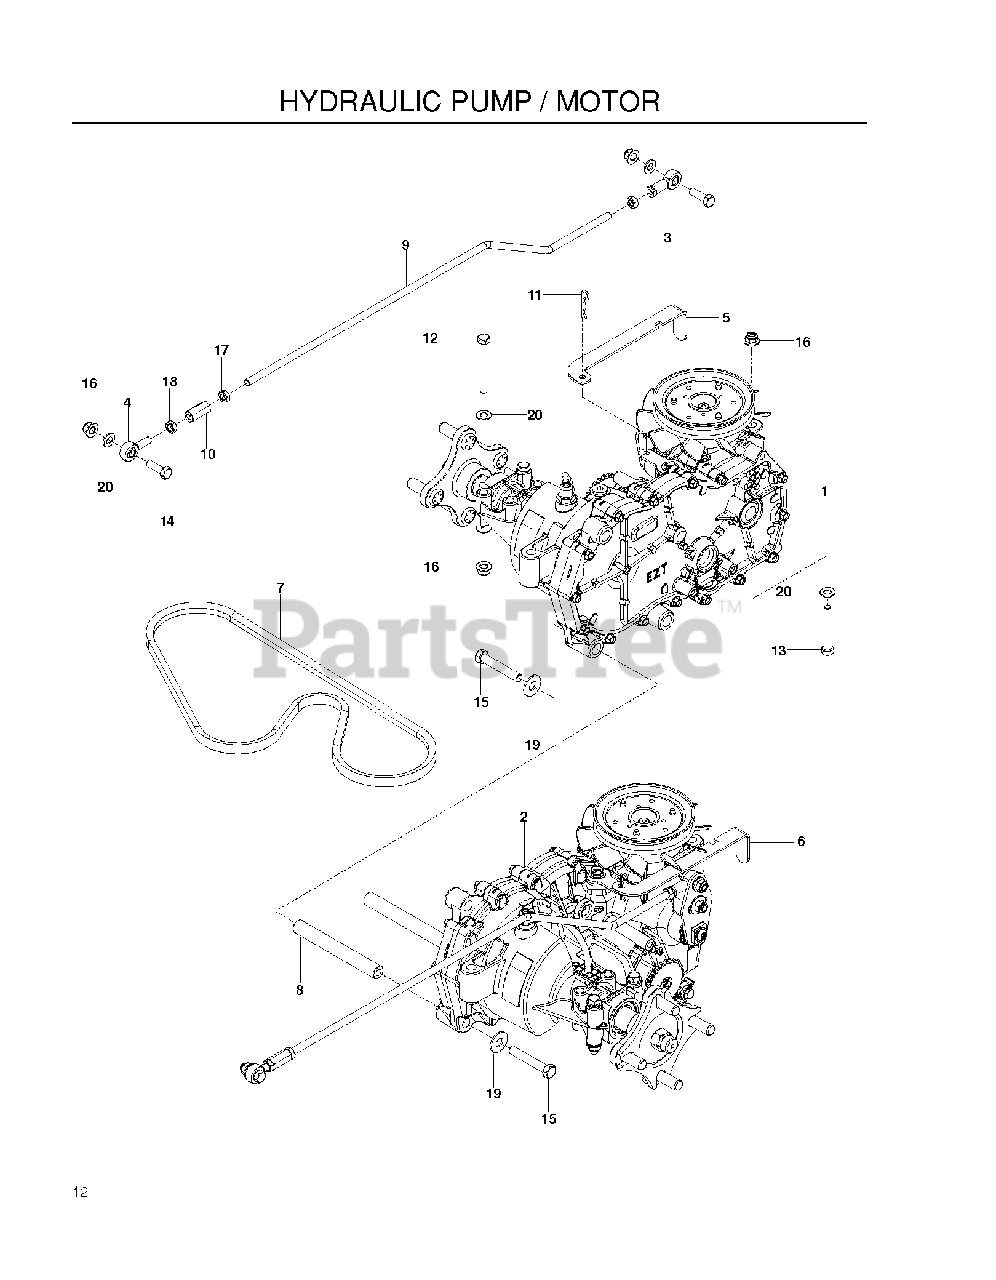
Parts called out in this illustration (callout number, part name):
1	HG_HYDRO RH
2	HG_HYDRO LH
3	RH ROD END
4	RB ROD.END.LH
5	RELEASE LEVER RH
6	RELEASE LEVER LH
7	BELT, EL 51.O4
8	SPACER, HYDRO
9	CONTROL ROD
10	ROD END COUPLER
11	HAIRPIN #2
12	HCS 5/16C X 2-3/4
14	HCS 5/16C X 1
15	HCS 3/8C X 2 1/4
16	5/16-18 NYLOC FLANGE NUT
17	NUT 5/16-24 UNF HEX JAM
18	NUT 5/16F LEFTHAND
19	RP WASHER 3/8 FLAT
20	FLAT WASHER 5/16 SAE
